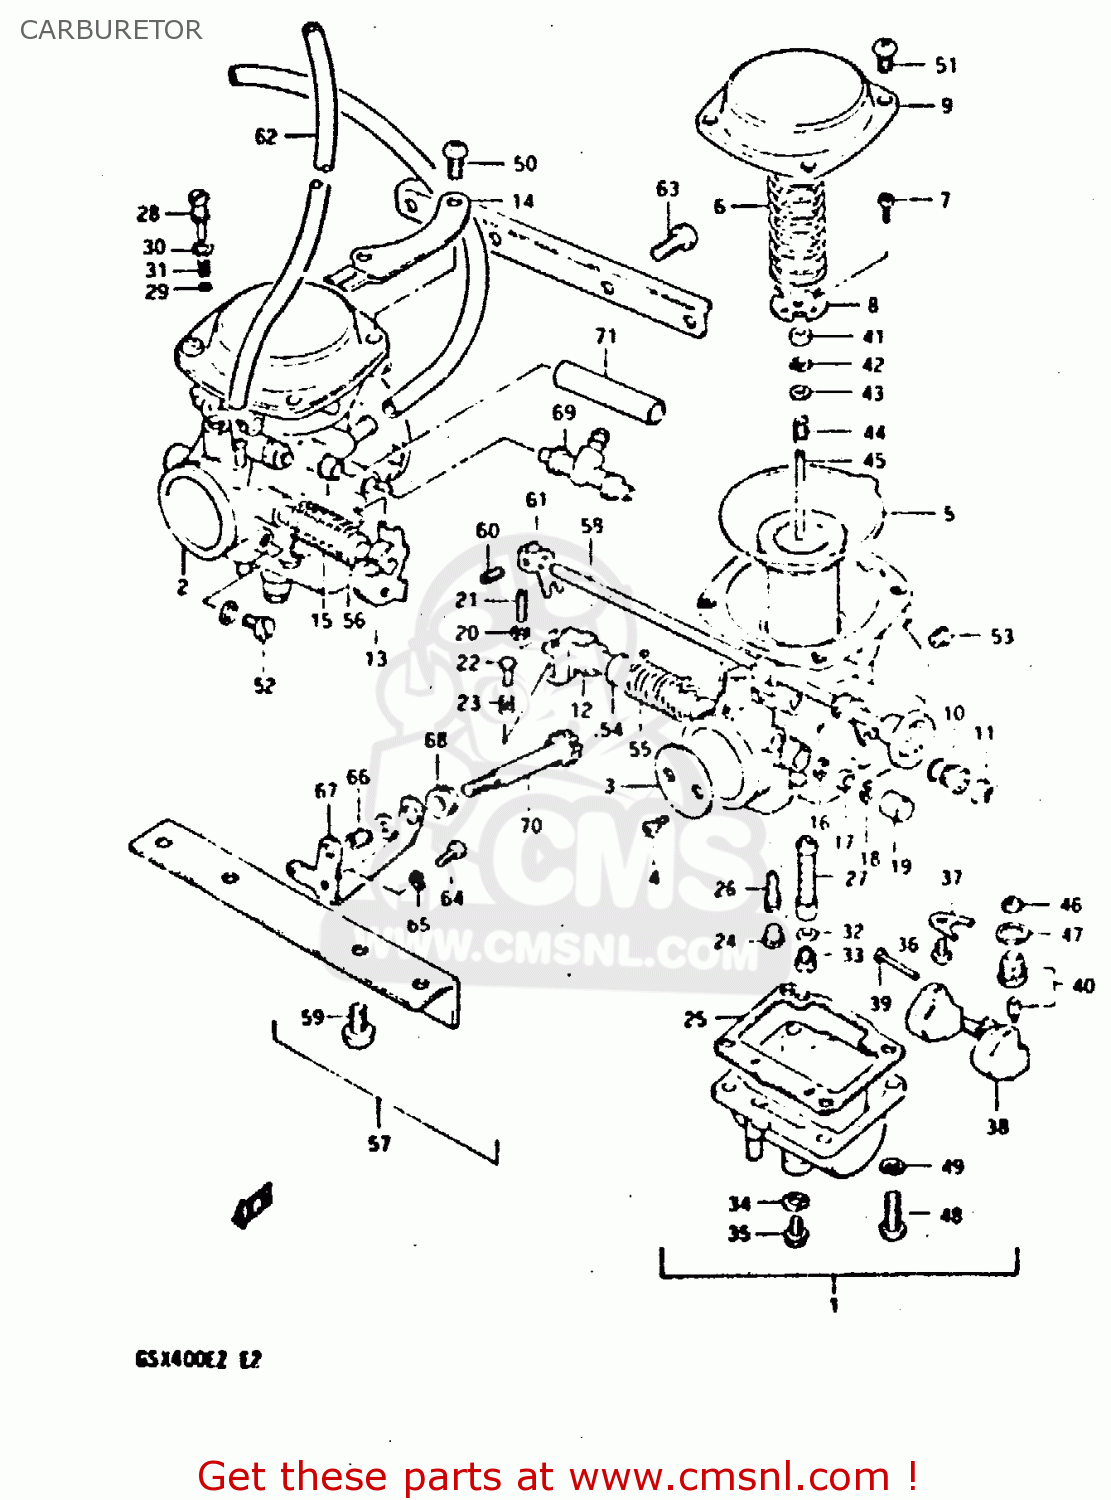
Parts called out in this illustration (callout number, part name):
1	CARBURETOR, LH
2	CARBURETOR, RH
3	VALVE,THROTTLE
4	SCREW
5	DIAPHRAGM
6	SPRING
7	SCREW
8	PLATE
9	COVER, DIAPHRAGM
10	O RING
11	CAP,STARTER VALVE
12	SHAFT ASSEMBLY
13	SHAFT,THROTTLE
14	BRACKET
15	SPRING
16	SEAL
17	GASKET,THROTTLE SHAFT (NAS)
18	E RING
19	CAP
20	NUT
21	SCREW
22	PIN,THROTTLE LEVER
23	SPRING
24	PLUG,NEEDLE JET
25	GASKET,FLOAT CHAMBER (NAS)
26	JET, PILOT (42.5)
27	JET,NEEDLE(P-1)
28	SCREW,PILOT AIR
29	O-RING
30	GASKET
31	SPRING
32	WASHER,NEEDLE NOZZLE
33	JET
34	GASKET (NAS)
35	PLUG,DRAIN
36	SCREW 4X6
37	PLATE,NEEDLE VALVE FITING
38	FLOAT
39	PIN,FLOAT
40	VALVE ASSEMBLY,NEEDLE
41	RING
42	E-RING
43	PIN,FLOAT
44	SPRING
45	NEEDLE,JET
46	FILTER
47	O-RING,NEEDLE VALVE
48	SCREW
49	LOCK WASHER
50	SCREW
51	SCREW
52	SCREW
53	JET,AIR(125)
54	SPACER,THROTTLE SHAFT
55	SPRING
56	SPACER,THROTTLE SHAFT
57	FLANGE ASSY
58	SHAFT,STARTER
59	SCREW 6X12
60	SCREW
61	LEVER
62	HOSE
63	SCREW
64	SCREW
65	LOCK WASHER
66	SPRING,THROTTLE ADJUST
67	BRACKET,THROTTLE ADJUST
68	CAP,RUBBER
69	NIPPLE,CARBURETOR
70	SCREW
71	HOSE (5*8*300)
